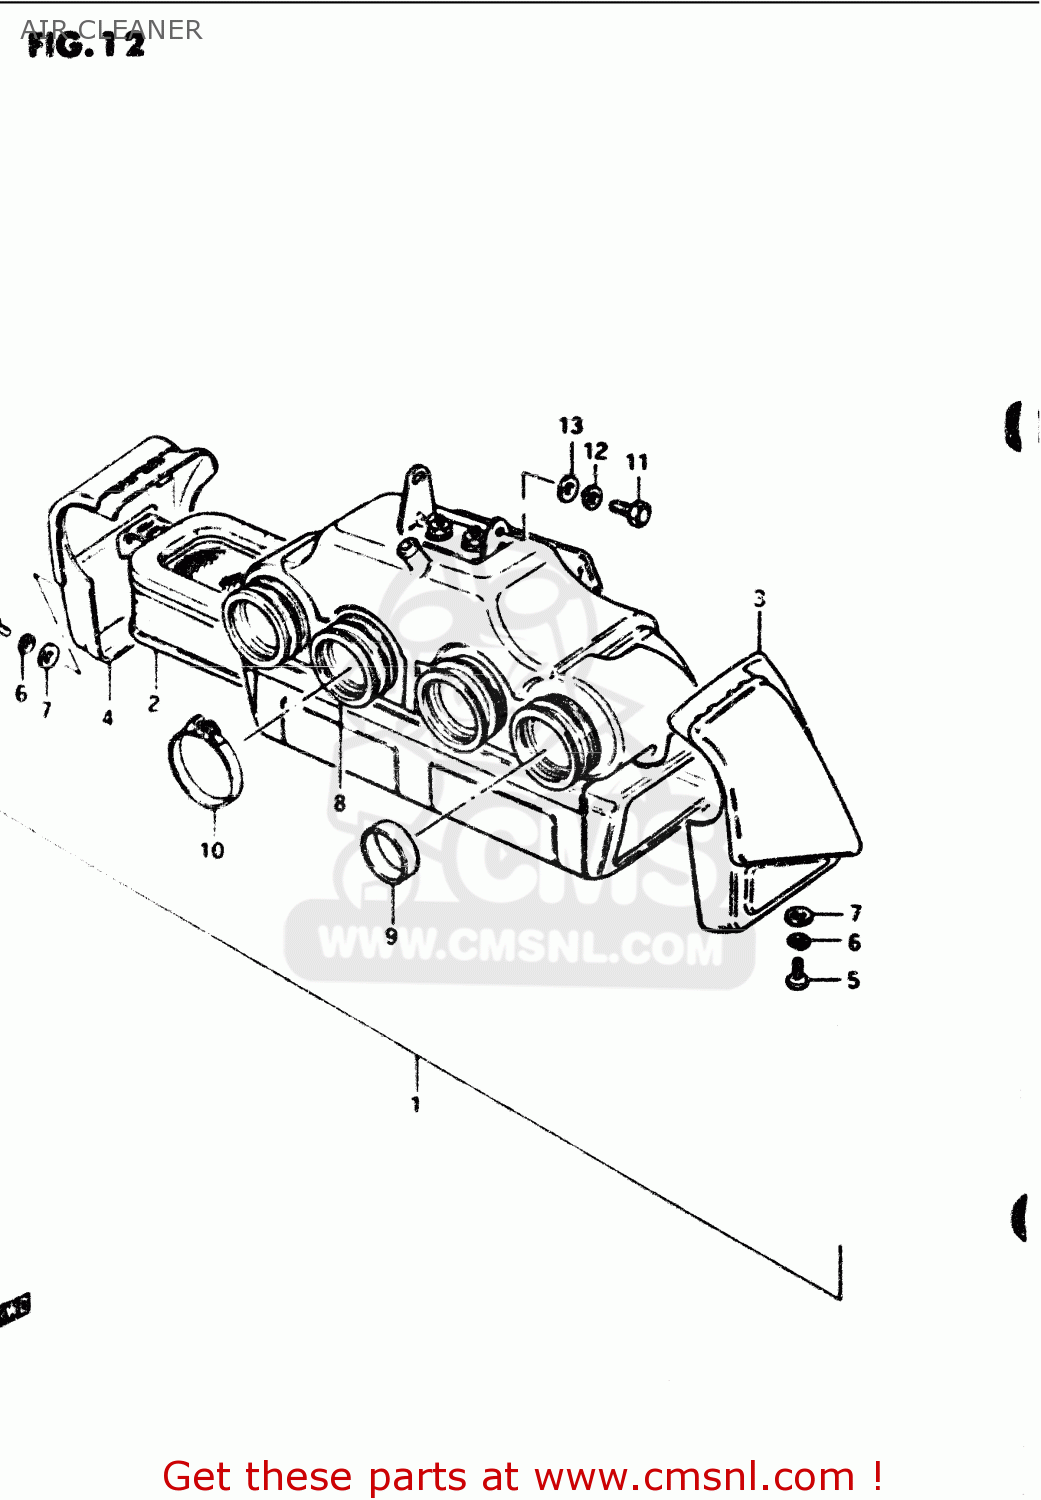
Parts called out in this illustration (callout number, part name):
1	CLEANER ASSEMBLY,AIR
2	FILTER ASSY
3	CAP,AIR CLEANER
4	CAP,AIR CLEANER
5	SCREW
6	LOCK WASHER
7	WASHER
8	TUBE,OUTLET
9	RING,CARBURETOR AIR IN
10	CLAMP
11	BOLT
12	LOCK WASHER
13	WASHER
